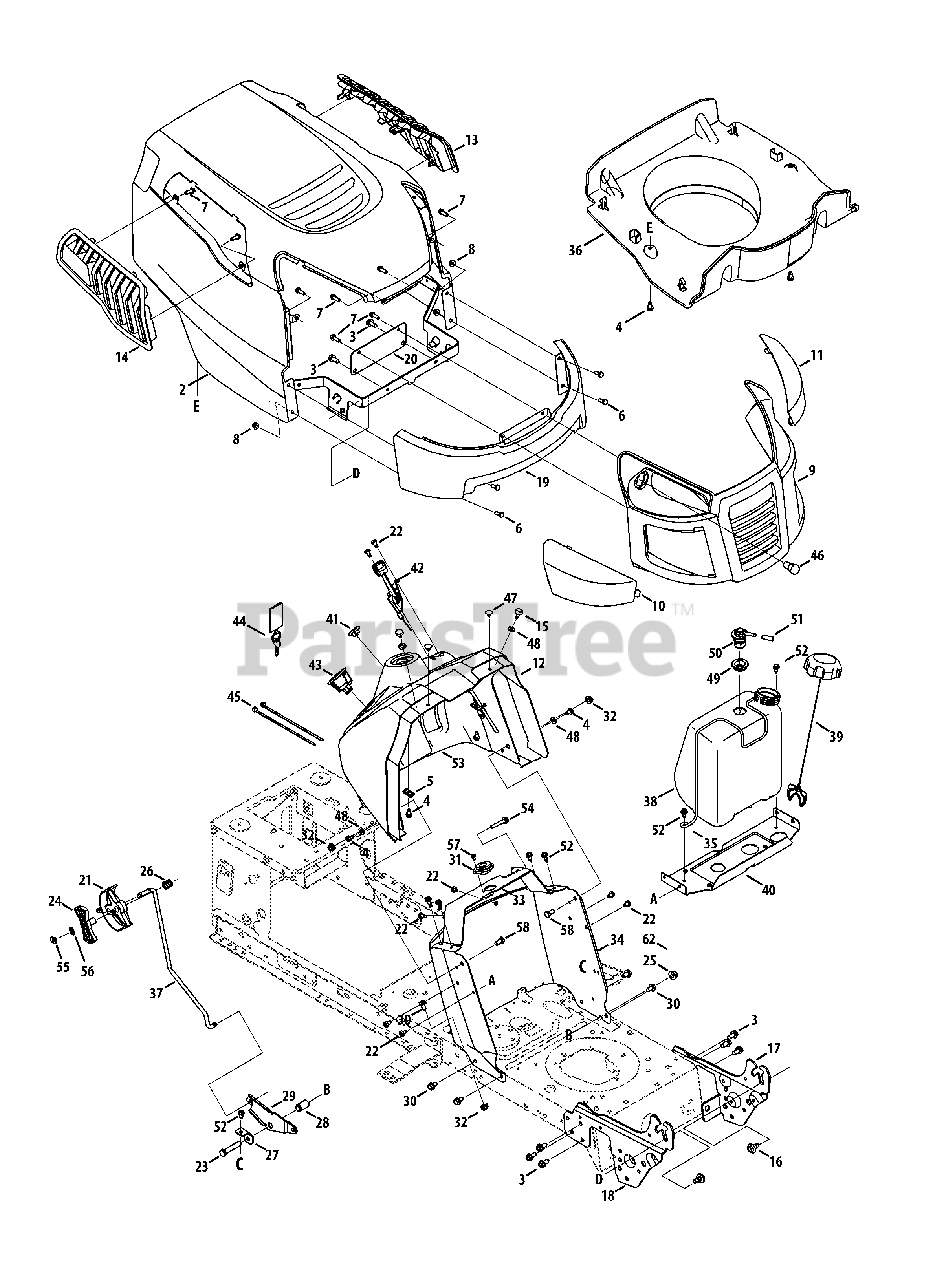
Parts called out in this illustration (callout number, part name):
1	Bulb Socket
2	Hood Assembly
3	Screw, 5/16-18 x .750
4	Hex Washer Screw, 1/4-20 x .500
5	Tin Clip Nut, 1/4-20
6	Hex Screw, 1/4-20 x .620
7	Screw, 1/4 x .750
8	Nut, Hex Flange Insert Lock, 1/4-20
10	Headlight Lens, RH
11	Headlight Lens, LH
12	Dash Collar
13	Hood Scoop, LH
14	Hood Scoop, RH
15	Bumper
16	Shoulder Screw, 5/16-18
17	Left Support Pivot Bracket
18	Right Support Pivot Bracket
19	Lower Grill
20	Lower Grill Bracket
21	Shift Lever
22	Self-Tap Screw, 1/4-20
23	Hex Head Screw, 3/8-16
24	7-Speed Control Index
25	Nut, Hex Flange Insert Lock, 3/8-16
26	Compression Spring
27	Speed Latch Support Tab
28	Flange Spacer
29	Speed latch Bracket No RMC
30	Self-Tap Screw, 5/16-18
31	Steering Column Bearing
32	Nut, Hex Flange Lock, 5/16-18
33	Steering Support Bracket
34	Dash
35	Fuel Tank Support Rod
36	Plenum
37	Control Rod
38	Fuel Tank
39	Fuel Cap
40	Gas Tank Support Bracket
41	Choke Plug
42	Throttle/Choke Assembly
43	Key Switch Module
44	Key Assembly
45	Cable Tie
46	Headlight Bulb
47	Ratchet Clip, .250 x .500
48	Flat Washer, .25 x .630 x .0515
49	Rubber Grommet
50	Fuel Rollover Valve
51	Vent Hose
52	Hex Washer Screw, 1/4-20 x .625
53	Upper Dash
54	Hex Flange Bolt
55	Top Lock Weldnut
56	Lock Washer
57	Screw, #10
58	Hex Head Screw, 5/16-18
